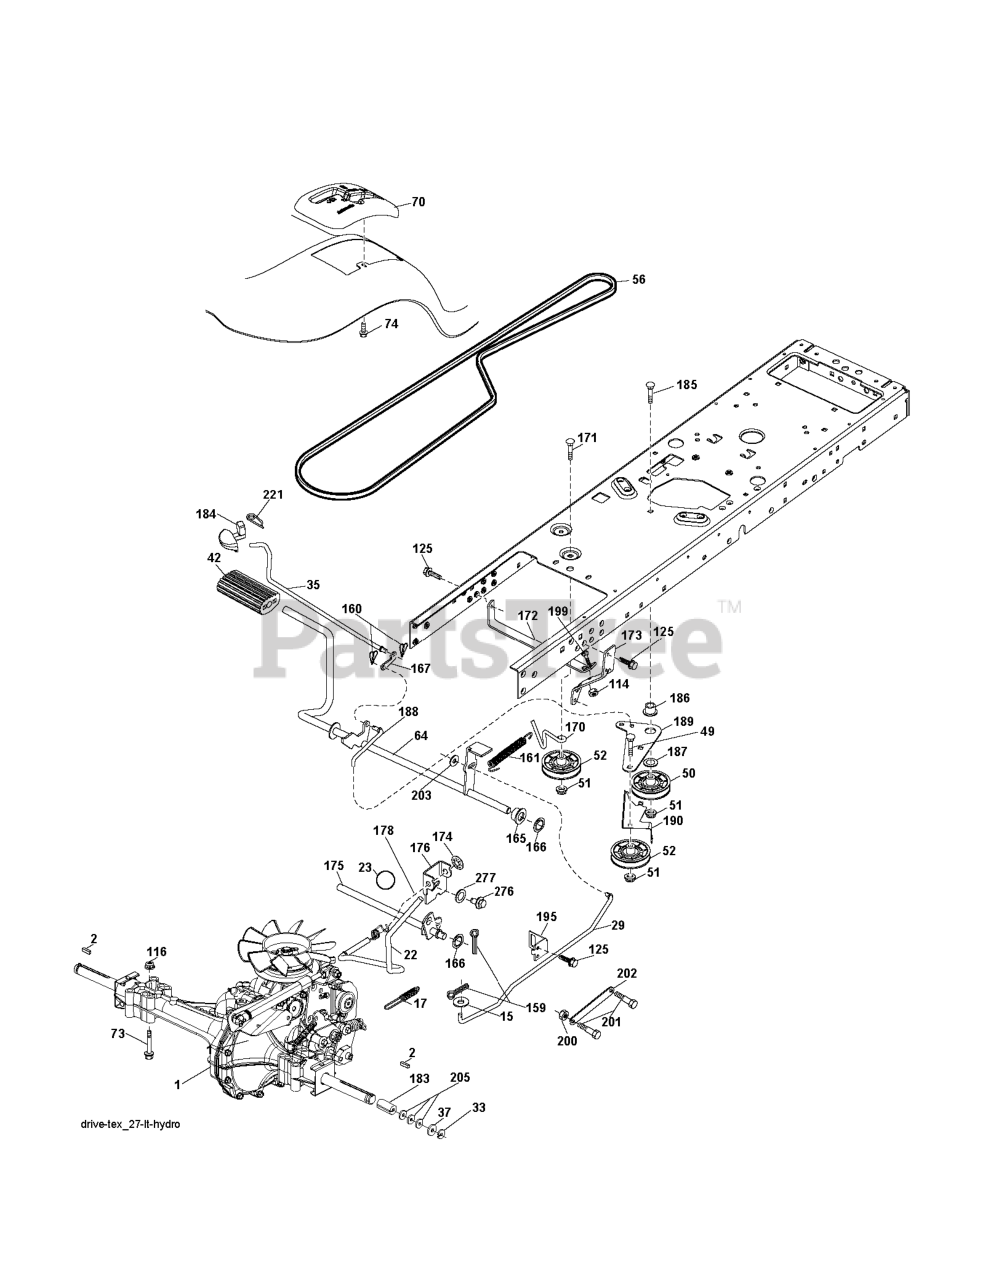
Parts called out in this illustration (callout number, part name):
2	SQUARE KEY
15	WASHER
17	SPRING.BRAKE.HG3000/3500
22	ROD.SHIFT.FENDER.TLT.2006
23	KNOB.DUCKHEAD.1/2
29	ROD.BRAKE.HG-0510
35	ROD.CNTRL.PARK.PREDATOR.LT.TEX
42	PEDAL COVER T
50	IDLER.FLAT.910.OFFSET
51	NUT LOCK FLG 3/8-16 UNC
52	IDLER.V-GROOVE.910.OFFSET
64	SHAFT.ASM.PEDAL.BRAKE.
70	CONSOLE SHIFT
73	BOLT HEX 5/16-18 GR 5
74	SCREW.HI-LO.CONSOLE
114	NUT.71038.31-18.HEX.NYLOCK
116	NUT LOCK HEX FLANGE 5/16-18
125	SCREW
159	COTTER PIN
160	RETAINER CLIP
161	SPRING.RETURN.CLUTCH.2006
165	BUSHING.SHAFT.BRAKE.HAND
166	NUT.PUSH.625.2006
167	LATCH.BRAKE.SPRING
170	KEEPER.V-IDLER.CENTER.
172	STRAP.TRQ.LH.FS.HG0510
173	STRAP TORQUE RH
174	NUT.PUSH.500.2006
175	SHAFT.ASM.SHFT.HG0510/
176	ARM.CLEVIS.ROD.SHIFT
178	SPRING.SHIFT.GT2006
183	SPACER AXLE
184	HANDLE PARKING BRAKE
186	SPACER.RETAINER
187	WASHER 12/32X2X10GA
188	RP.LINK.CLUTCH.GROUND.DRIVE
189	BRACKET.PULLEY.IDLER.W/TEX
190	KEEPER.BELLCRANK.DRIVE
195	BRKT.ROD.BRAKE.18/20/2
200	NUT.CENTERLOCK.5/16-
201	BOLT SHOULDER 5/16-18 UNC
203	WASHER
221	RETAINER.SPRING.CLIP.H
276	BOLT FIN HEX 7/16-14 X 1
277	WASHER SERRATED
